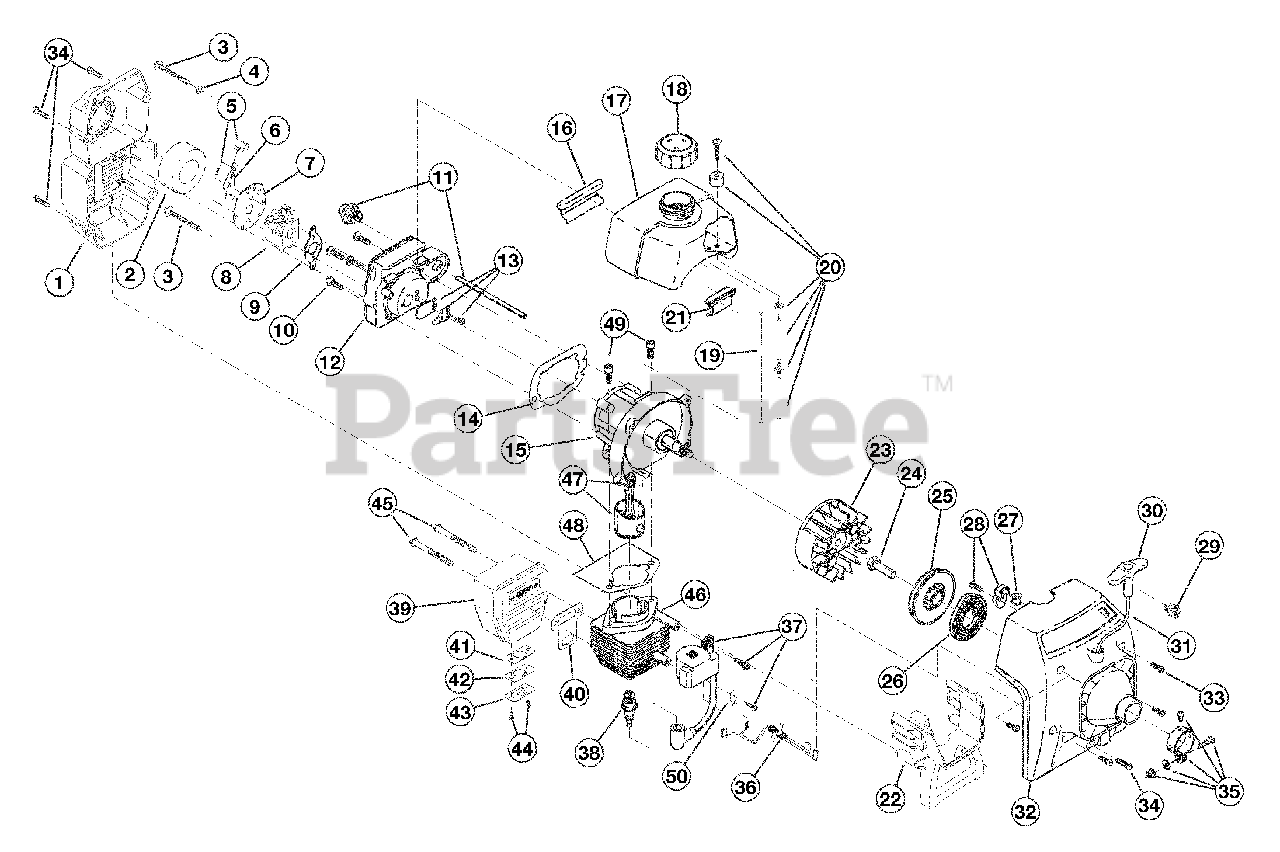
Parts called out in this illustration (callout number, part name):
1	Air Cleaner/Muffler Cover Assembly
2	Air Cleaner Filter
3	Carburetor Mounting Screws
4	Wavey Washer
5	Choke Knob & Screw
6	Choke Lever Assembly
7	Choke Lever & Plate
8	Carburetor Assembly
9	Carburetor Gasket
10	Carb Mount Screw
11	Primer and Hose Assembly
12	Carburetor Mount Assembly
13	Reed Assembly
14	Carburetor Mount Gasket
15	Crankcase Service Assembly
16	Rear Mounting Pad
17	Fuel Tank Assembly
18	Fuel Cap Assembly
19	Fuel Return Line
20	Fuel Line Assembly
21	Front Mounting Pad
22	Shroud Extension and Stand
23	Flywheel Assembly
24	Square Nut Drive
25	Recoil Pulley
26	Recoil Spring
27	Rope Guide
28	Pulley Retainer Assembly
29	Switch Assembly
30	Pull Handle
32	Starter Housing Assembly
33	Housing Screw
34	Cover Screw
35	Upper Clamp Assembly
36	Wire Lead
37	Module Assembly
38	Spark Plug
39	Muffler Assembly
40	Exhaust Gasket
41	Spark Arrestor
42	Exhaust Hood Diverter
43	Exhaust Hood
44	Screw
45	Muffler Mounting Bolt Assembly
46	Cylinder Assembly
47	Piston & Rod Assembly
48	Cylinder Gasket
49	Cylinder Bolt
50	Ground Tab
